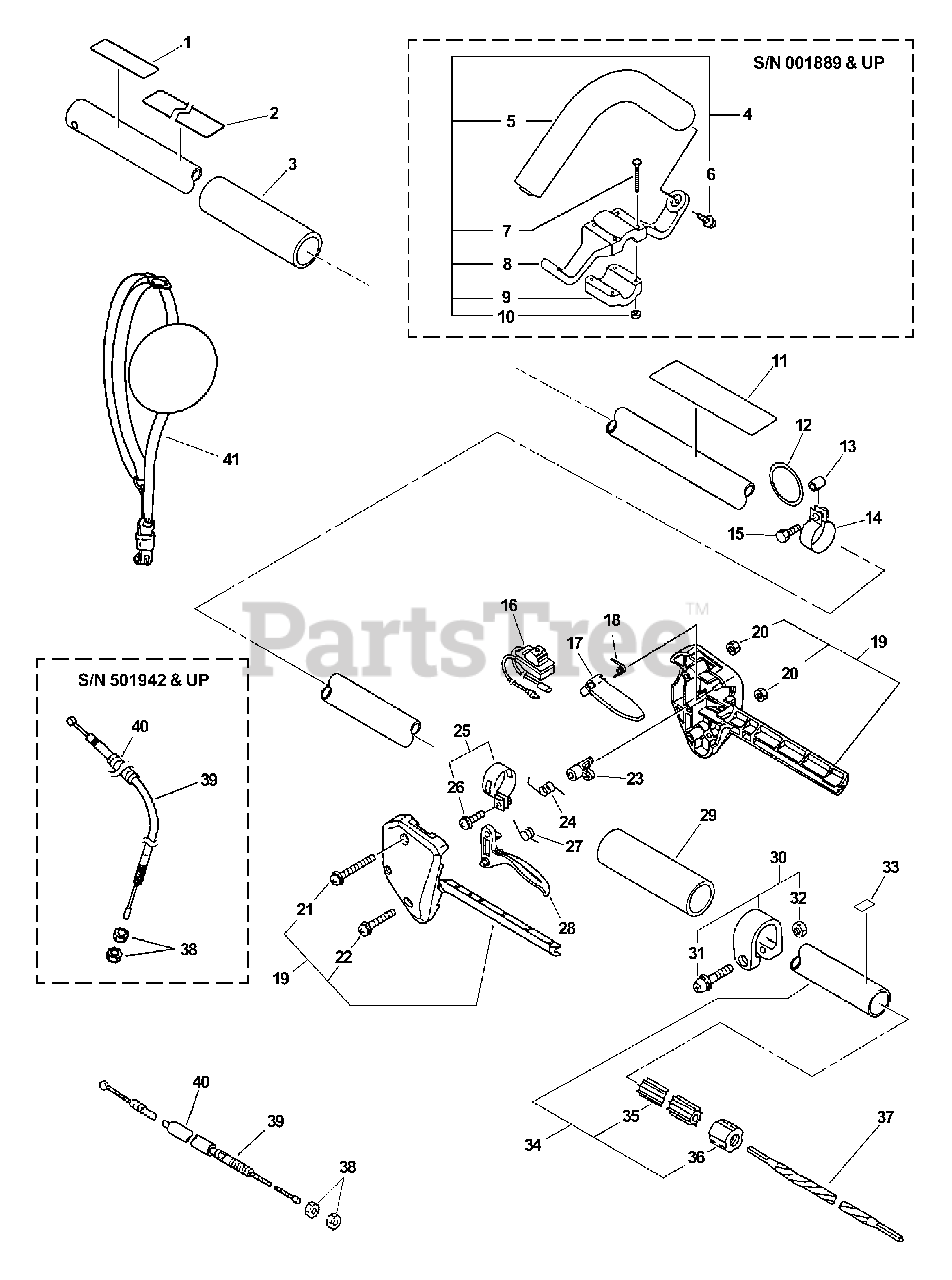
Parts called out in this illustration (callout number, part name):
1	LABEL - CAUTION -- SPANISH
2	LABEL - CAUTION
3	GRIP, HANDLE
4	LOOP HANDLE ASSY
5	HANDLE - FRONT
6	SCREW - 5X14
7	SCREW - 5X35
8	BRACKET, HANDLE - UPPER
9	BRACKET, HANDLE - LOWER
11	LABEL - CAUTION
15	BOLT - 5X18
16	IGNITION SWITCH ASSY
17	LEVER, TRIGGER LOCKOUT
18	SPRING, LOCKOUT LEVER
19	THROTTLE BRACKET SET
21	SCREW - 5X35
22	SCREW - 5X25
23	LOCKOUT, THROTTLE
24	SPRING, TRIGGER
25	CLAMP KIT
26	SCREW - 5X14
27	SPRING, TRIGGER
28	TRIGGER, THROTTLE
29	GRIP, HANDLE
30	CLAMP KIT
31	SCREW - 5X28
33	LABEL - ALIGNMENT
34	MAIN PIPE ASSY
35	LINER - FLEXIBLE
37	DRIVESHAFT - FLEXIBLE
39	CABLE, THROTTLE
40	TUBE - VINYL
41	SHOULDER STRAP ASSY
